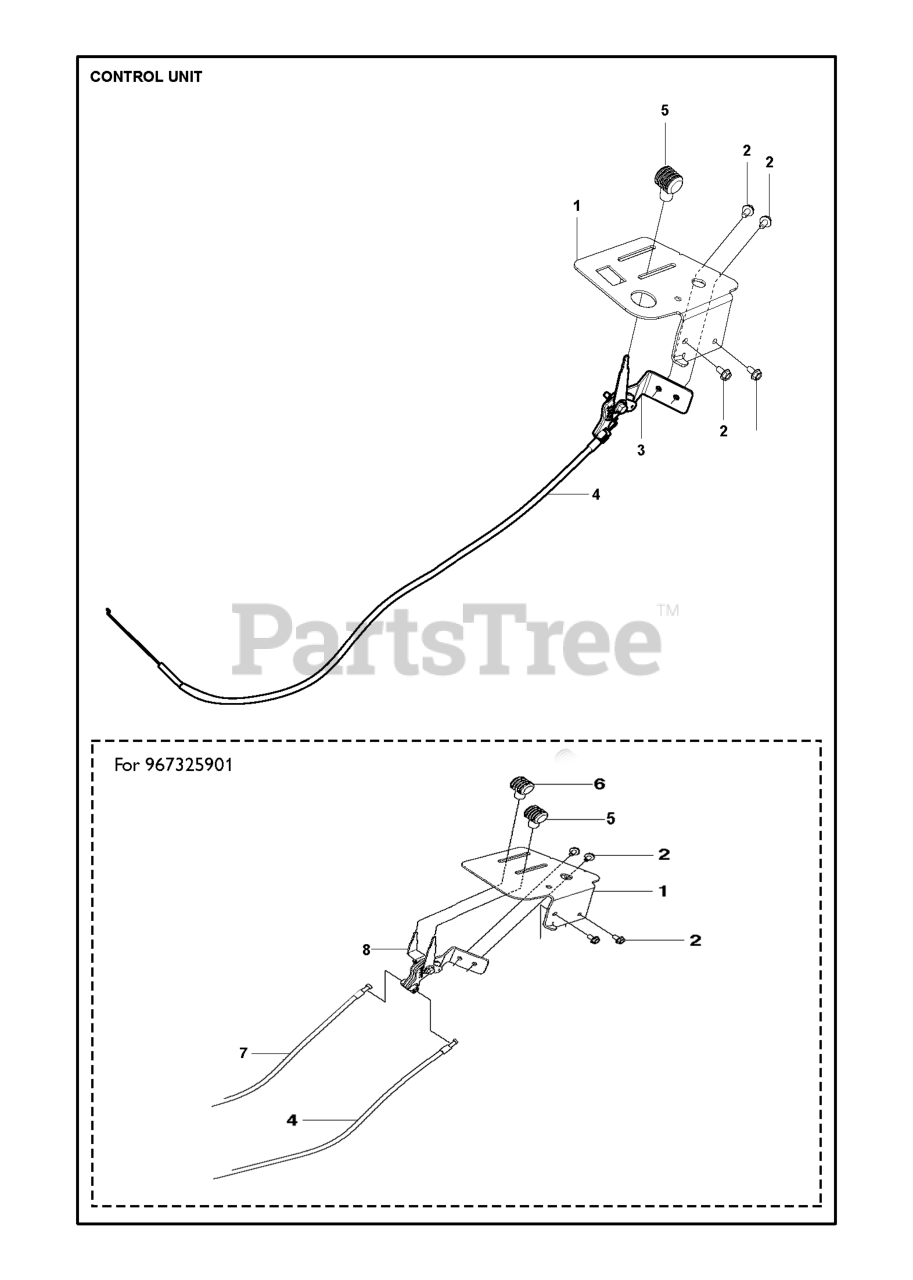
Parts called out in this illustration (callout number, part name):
2	SCREW EHHFM
3	THROTTLE CONTROL ASSY SINGLE
6	KNOB
7	WIRE
8	THROTTLE CONTROL
